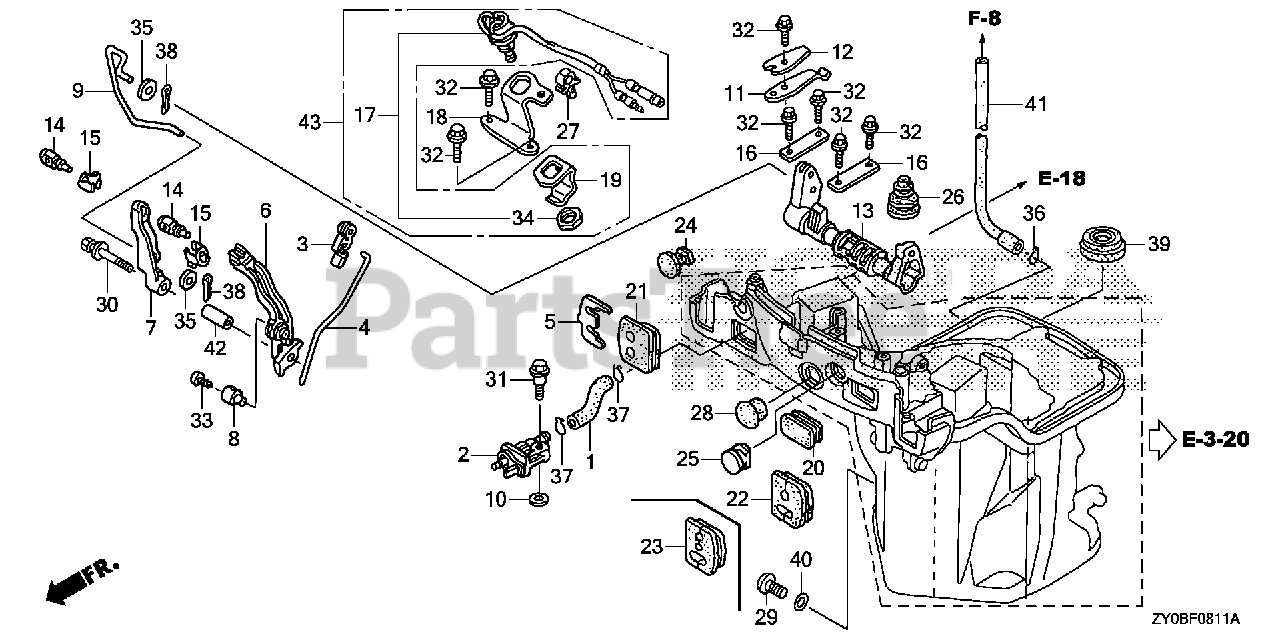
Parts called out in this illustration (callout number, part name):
1	TUBE A, FUEL
1	TUBE A, FUEL (FKM)
2	CONNECTOR ASSY., FUEL (B)
3	LINKAGE, PIVOT
4	ROD, THROTTLE
5	PLATE, REMOTE CONTROL CABLE
6	ARM, THROTTLE REMOTE
7	ARM, SHIFT LINK
8	HOLDER, THROTTLE ROD
9	ROD, SHIFT LINK
10	WASHER, PIVOT
11	SPRING, CLICK
12	SPRING, CLICK ASSIST
13	SHAFT, SHIFT
14	PIVOT, SHIFT
15	PLATE, LOCK
16	PLATE, SHIFT SHAFT
17	SWITCH ASSY., NEUTRAL
18	BRACKET, NEUTRAL SWITCH
19	PLATE, NEUTRAL SWITCH
20	GROMMET G, OIL CASE
21	GROMMET A, OIL CASE
23	GROMMET B, OIL CASE (PT)
24	GROMMET F, OIL CASE
25	GROMMET D, OIL CASE
26	GROMMET E, OIL CASE
27	CLIP, BRAKE PIPE (A)
28	CAP, HANDLE (LOWER)
29	BOLT, OIL CHECK
30	BOLT-WASHER (6X40)
31	BOLT, SPECIAL (6X22) (CT200)
32	BOLT, FLANGE (5X12) (CT200)
33	BOLT, RECESSED (5X8)
34	NUT, HEX. (20MM)
35	WASHER, PLAIN (7MM)
36	CLIP, TUBE (B10)
37	CLIP, TUBE
37	CLIP, TUBE (B12)
38	PIN, SPLIT (2.0)
39	SEAL, WATER (15X28X6) (ENGINE NO.)
40	O-RING (5.5X1.5)
41	TUBE, WATER CHECK
42	COLLAR, DISTANCE (6X11X27)
